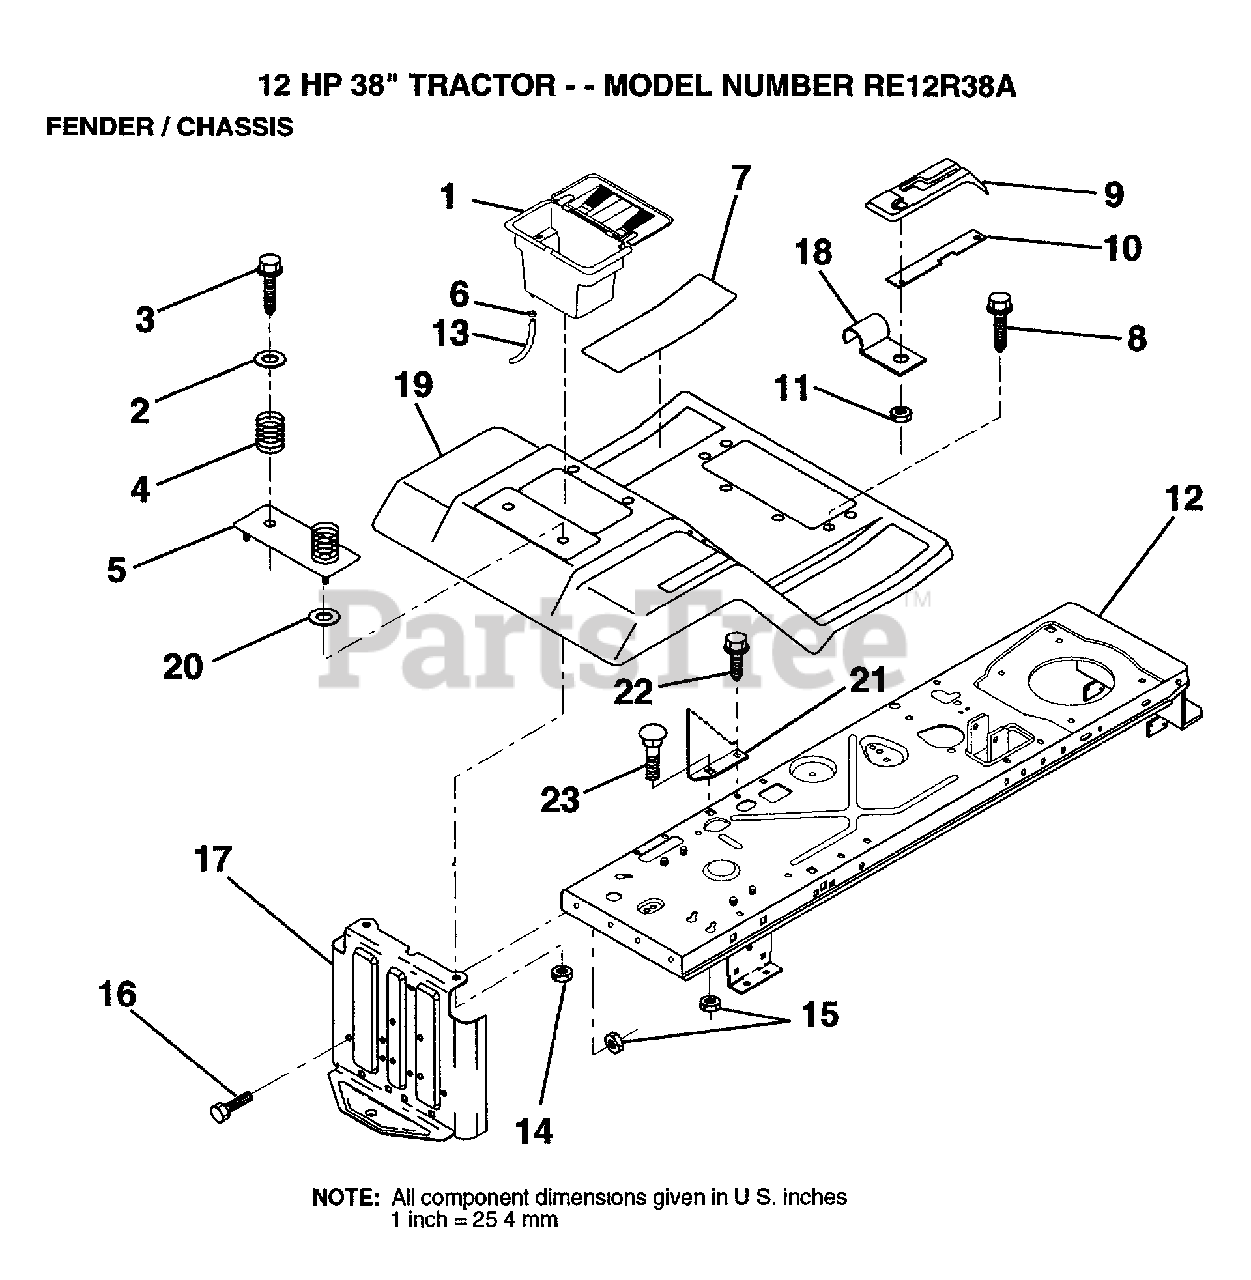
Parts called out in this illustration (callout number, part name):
2	WASHER
3	SCREW
4	SPRING COMPRESSIO
5	PLATE, BATTERY
6	HOSE CLAMP T
8	SCREW
10	BAR SHIFT LOCK
11	NUT
14	NUT
16	BOLT
17	DRAWBAR
18	CLIP,INSULATOR
22	SCREW LT
